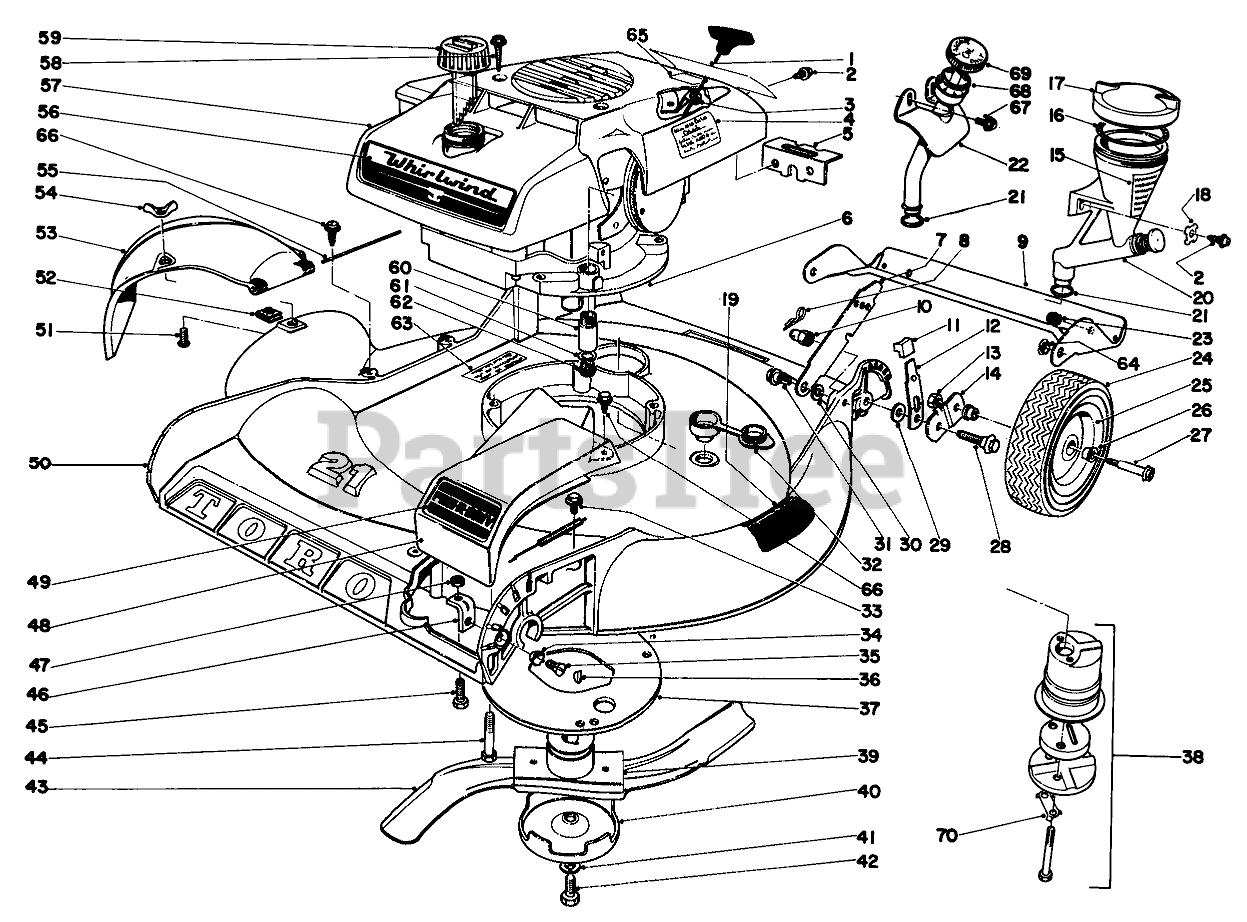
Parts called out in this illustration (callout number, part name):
1	Decal,Maintenance
2	Screw
3	Bracket,Recoil
4	Decal,Start
5	Bracket
6	Engine (Used on Model 20555)
7	Latch
8	PIN-COTTER, HAIR
9	Safety Shield, Rear
10	Nut
12	Spring Arm
13	Nut
14	Pivot Arm
15	Decal, Reservoir
16	"O" Ring
17	Cap, Reservoir (Incl. Ref. 16)(Used on Model 20227)
18	Washer
20	Reservoir, Oil
21	O-RING
22	Oiler Tube
23	SKID BUTTON
24	8 TIRE
25	Wheel Assy. (Incl. Ref. No.26)
26	FLANGE BUSHING
27	Wheel Bolt
28	Pivot Screw
29	WASHER-PIVOT
30	SPACER
31	SCREW-SHOULDER
32	Washer Plug
33	Screw
34	Lockwasher
36	KEY-WOODRUFF
37	Grass Guard
38	Muffler
39	BLADE RETAINER WA
40	ANTI-SCALP CUP
41	WASHER-LOCK
42	SPECIAL SCREW
43	Blade
44	Screw
45	SCREW
46	ADJ BRACKET
47	NUT-JAM
48	Guard, Belt
49	Decal
50	Housing
52	NUT-SPEED
53	Deflector
54	NUT-WING SPECL
55	HINGE PIN
56	Decal
57	Shroud
58	SCREW-HWH
59	Gas Cap
60	Extension Oil Drain
61	Gasket-Oil Drain
62	Plug Oil Drain
63	Decal
64	Nyliner
65	Decal-Warning
66	Screw
68	O-Ring
69	Dipstick
70	CLIP - LOCKING
